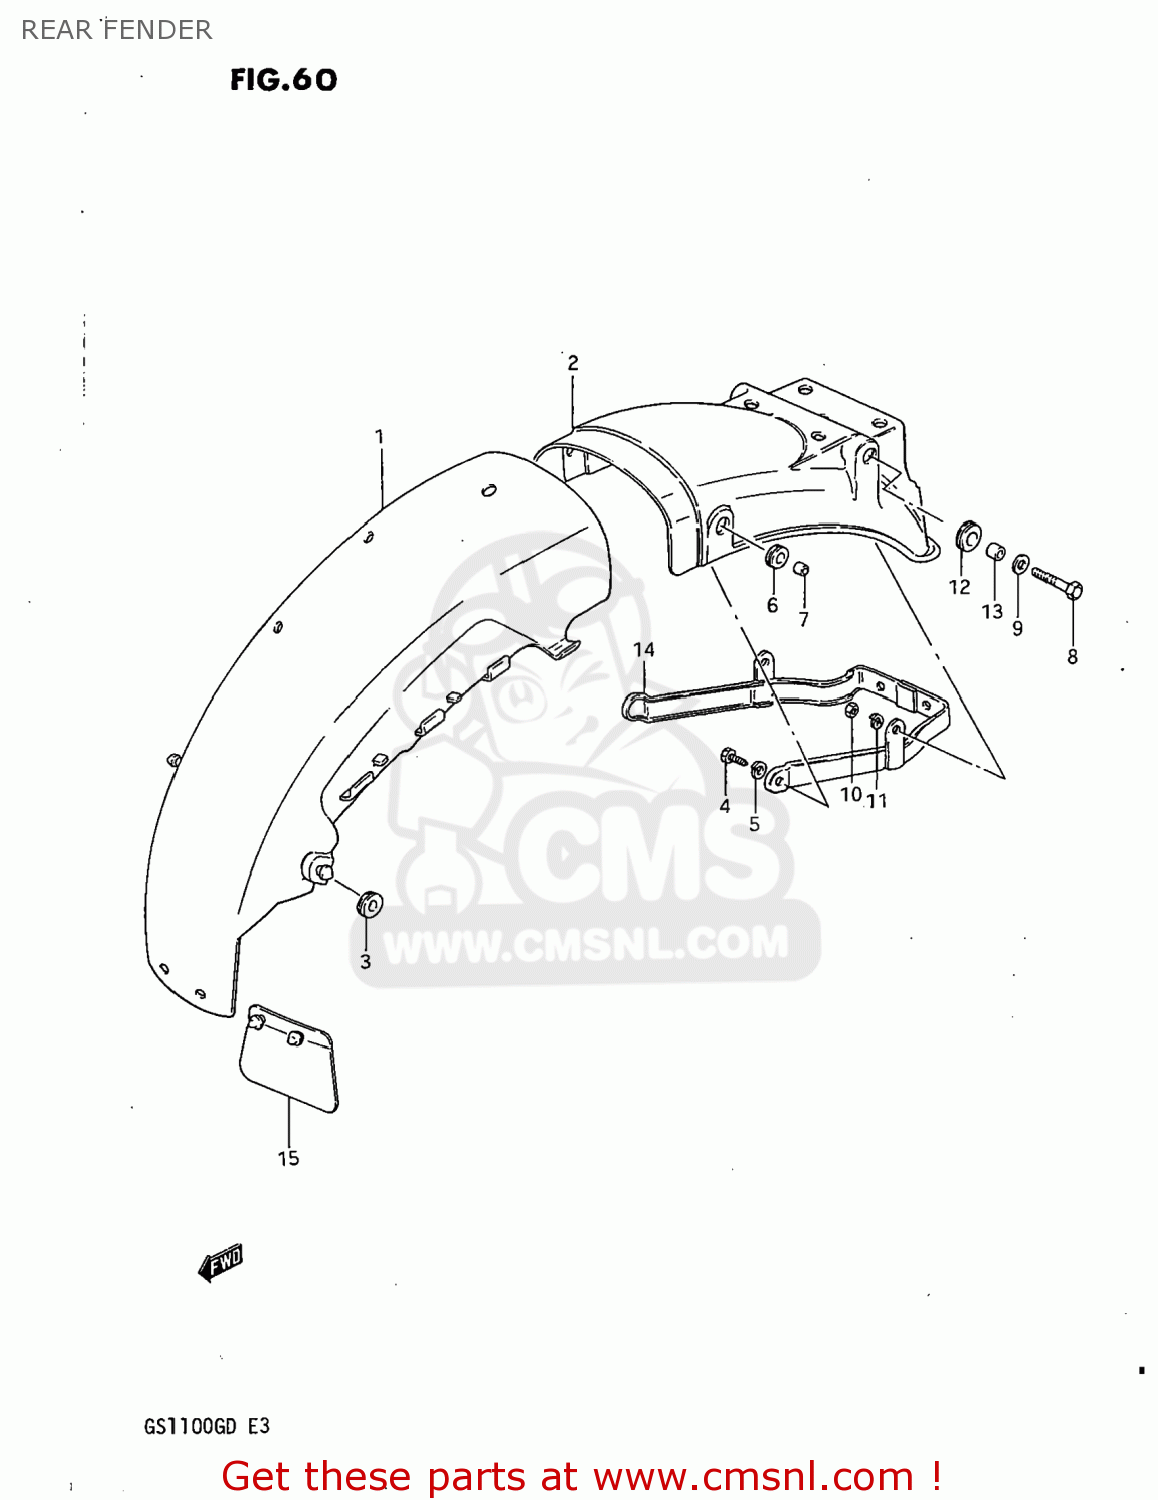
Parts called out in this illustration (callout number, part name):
1	FENDER,REAR
2	FENDER,REAR
3	CUSHION
4	BOLT, UPPER
5	LOCK WASHER
6	CUSHION
7	SPACER(6.1X9X7.5)
8	BOLT (8X30)
9	WASHER
10	NUT
11	LOCK WASHER
12	CUSHION
13	SPACER (8.2X12X7.5)
14	REINFORCEMENT,REAR FENDER
15	GUIDE,RR FENDER MUD
